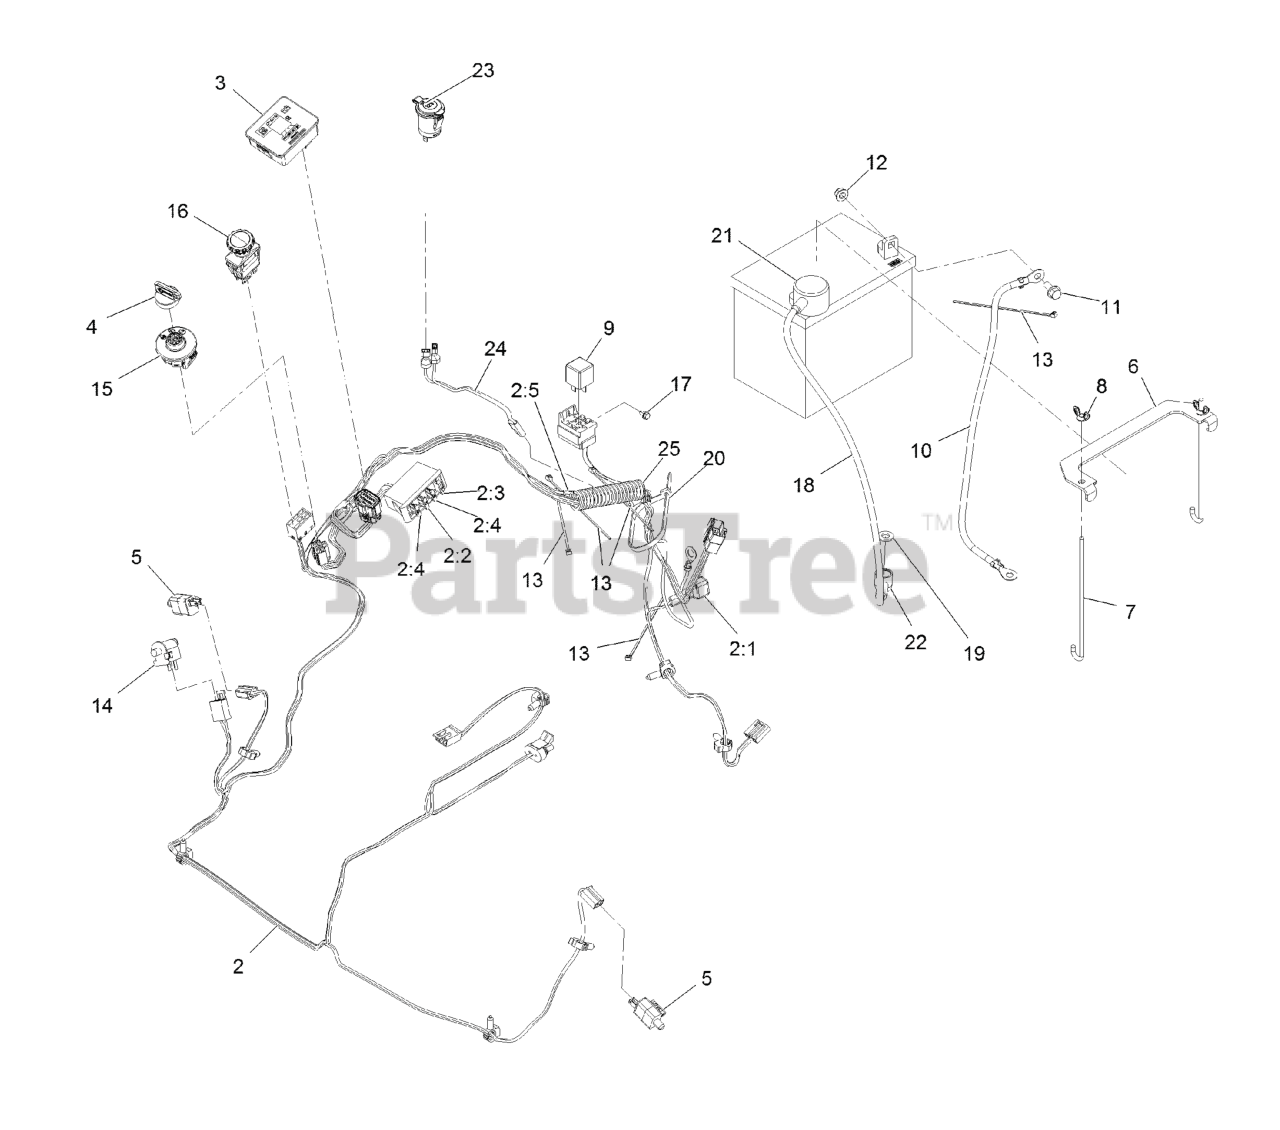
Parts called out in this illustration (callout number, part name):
2	HARNESS-WIRE, MAIN
2:2	FUSE-BLADE, 10 AMP
2:3	FUSE-BLADE, 15 AMP
2:4	FUSE-BLADE, 25 AMP
2:5	CAP-PLUG
3	FUEL/HOUR METER ASM
4	KEYS-IGNITION (SPARE PAIR
4	KEY-IGNITION
6	STRAP-TIE DOWN, BATTERY
7	BOLT-HOLDDOWN
8	WINGNUT
10	CABLE-BATTERY, NEGATIVE
11	SCREW-HHF
12	NUT-HF, NI
13	TIE-CABLE
14	SWITCH-BAIL
15	SWITCH-IGNITION
16	SWITCH-PTO, 10 AMP
17	SCREW-HWH
18	CABLE-BATTERY, POSITIVE
19	WASHER-FLAT
20	TIE-PLASTIC
21	INSULATOR-BATTERY
22	INSULATOR-SOLENOID
23	PORT-POWER, 12V
24	HARNESS, RECEPTACLE 12V
25	COVER-HOSE
